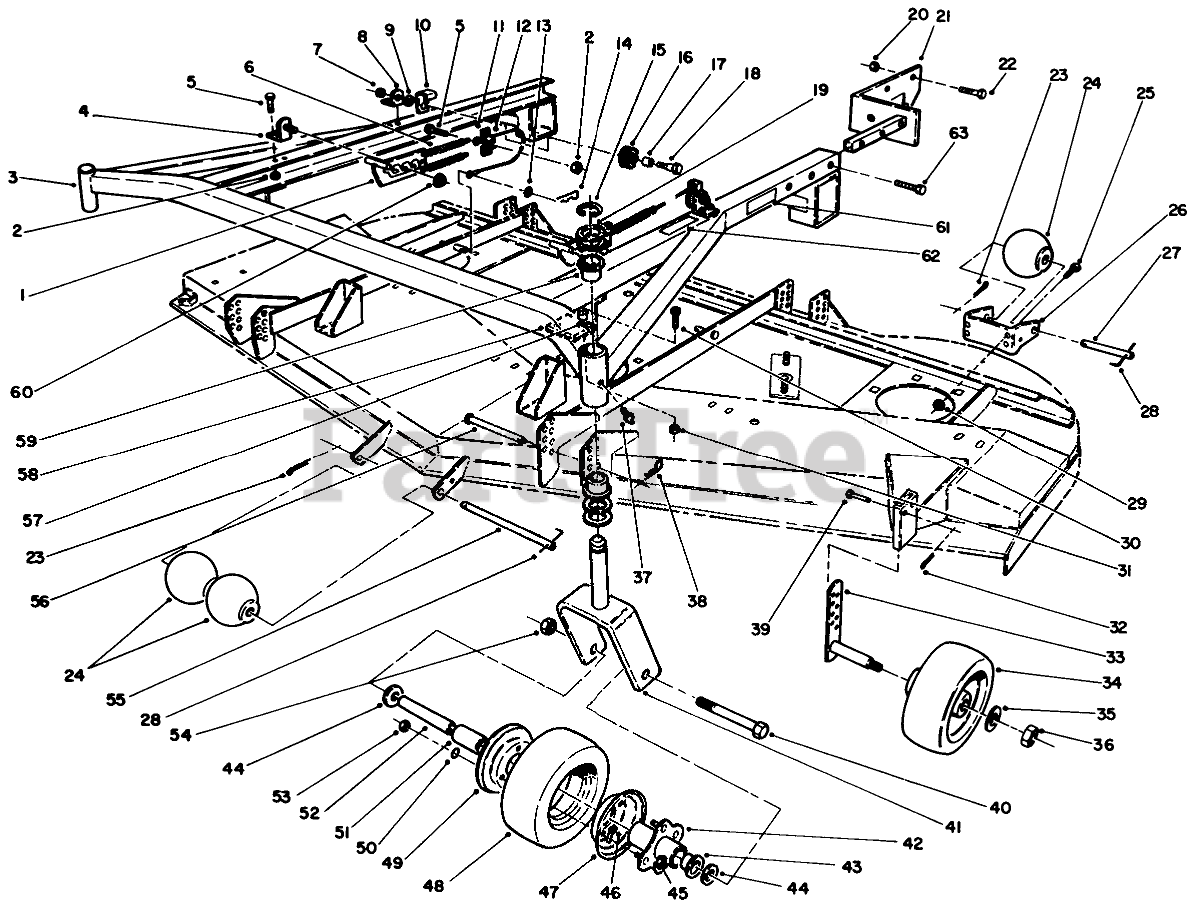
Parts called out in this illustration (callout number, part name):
1	Control-Tension
2	NUT-LOCK, NI
3	Carrier Frame Assembly (Incl. Decal 14-1529)
4	Bracket-Control
5	SCREW-HH
6	EXTENSION SPRING
7	NUT-LOCK, NI
8	Bracket-Pulley
9	THRUST WASHER
10	CABLE RETAINER
11	SPRING BRACKET
12	CABLE
13	WASHER-FLAT
14	PIN-COTTER
15	RING-RETAINING
16	Pulley Assembly (Incl. Ref.#17)
17	BUSHING
18	BOLT-SHOULDER
19	Washer-Thrust
20	NUT-HF
21	Lift Arm Assembly L.H.
22	SCREW-HHF
23	PIN-COTTER
24	ROLLER
25	SCREW-HH
26	Bracket-Roller
27	SHAFT-ROLLER
28	PIN-SPECIAL
29	NUT-HHF, WHIZ
31	NUT-LOCK, NI
32	PIN-HAIR
33	GAGE-WHEEL
34	WHEEL-GAGE
35	WASHER-FLAT
36	NUT-LOCK, NI
37	FITTING-GREASE
38	PIN-HAIR
39	PIN-CLEVIS
40	SCREW-HH
41	Castor Fork
42	HUB-CENTER
43	BEARING-OUTSIDE
44	WASHER-FLAT
45	FITTING-GREASE
46	TUBE-INNER (W/VALVE)
47	FEMALE WHEEL HALF
49	MALE WHEEL HALF
50	WASHER-LOCK
51	BEARING-ROLLER
52	SPANNER-TIRE
53	NUT-HEX
54	NUT-HEX
55	SHAFT-ROLLER
56	Pin-Clevis
57	SPACER
58	CUSHION-RUBBER
59	Bushing
60	NUT-HF
61	Decal-H.O.C.
62	DECAL-WARNING
63	Screw-Hex. Hd. Cap
